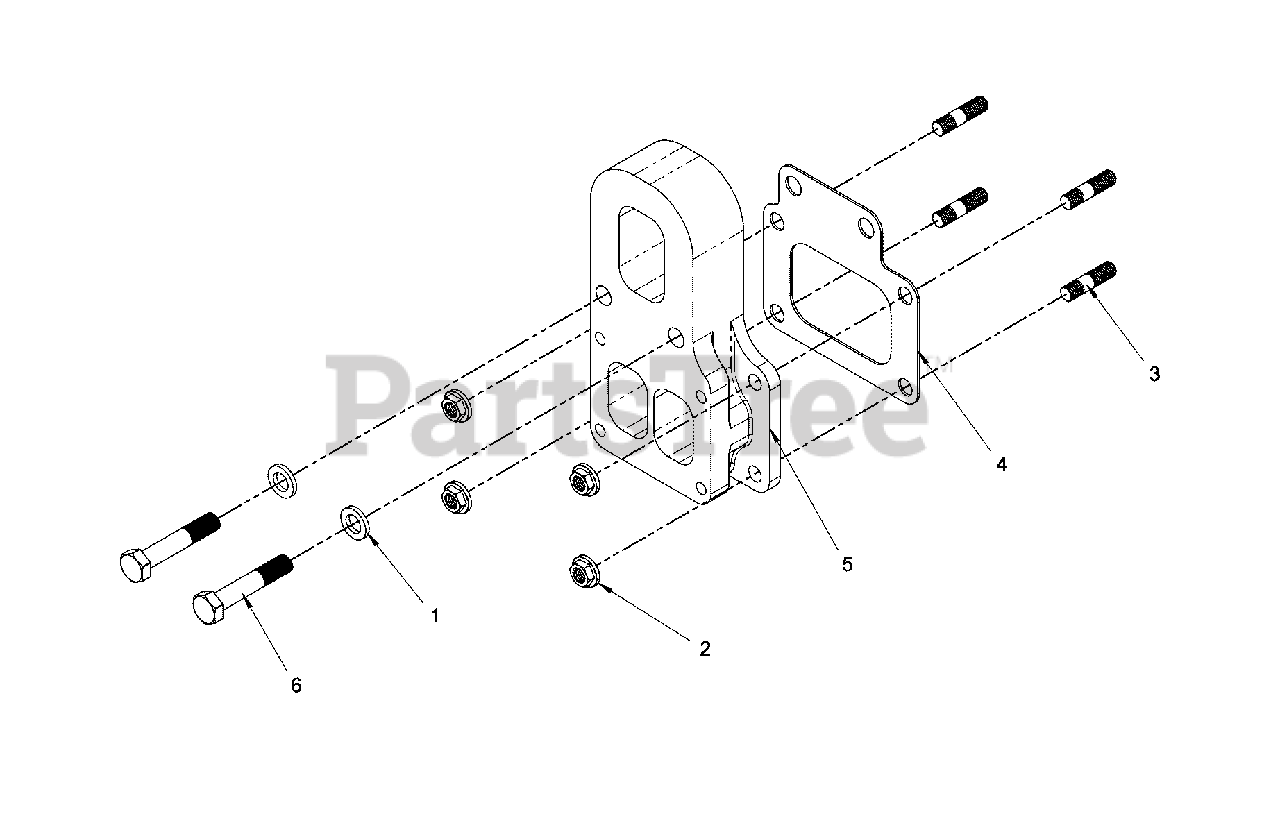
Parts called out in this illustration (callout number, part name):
1	* WASHER
2	* NUT
3	* STUD
4	GASKET
5	* ADAPTER
6	* BOLT
